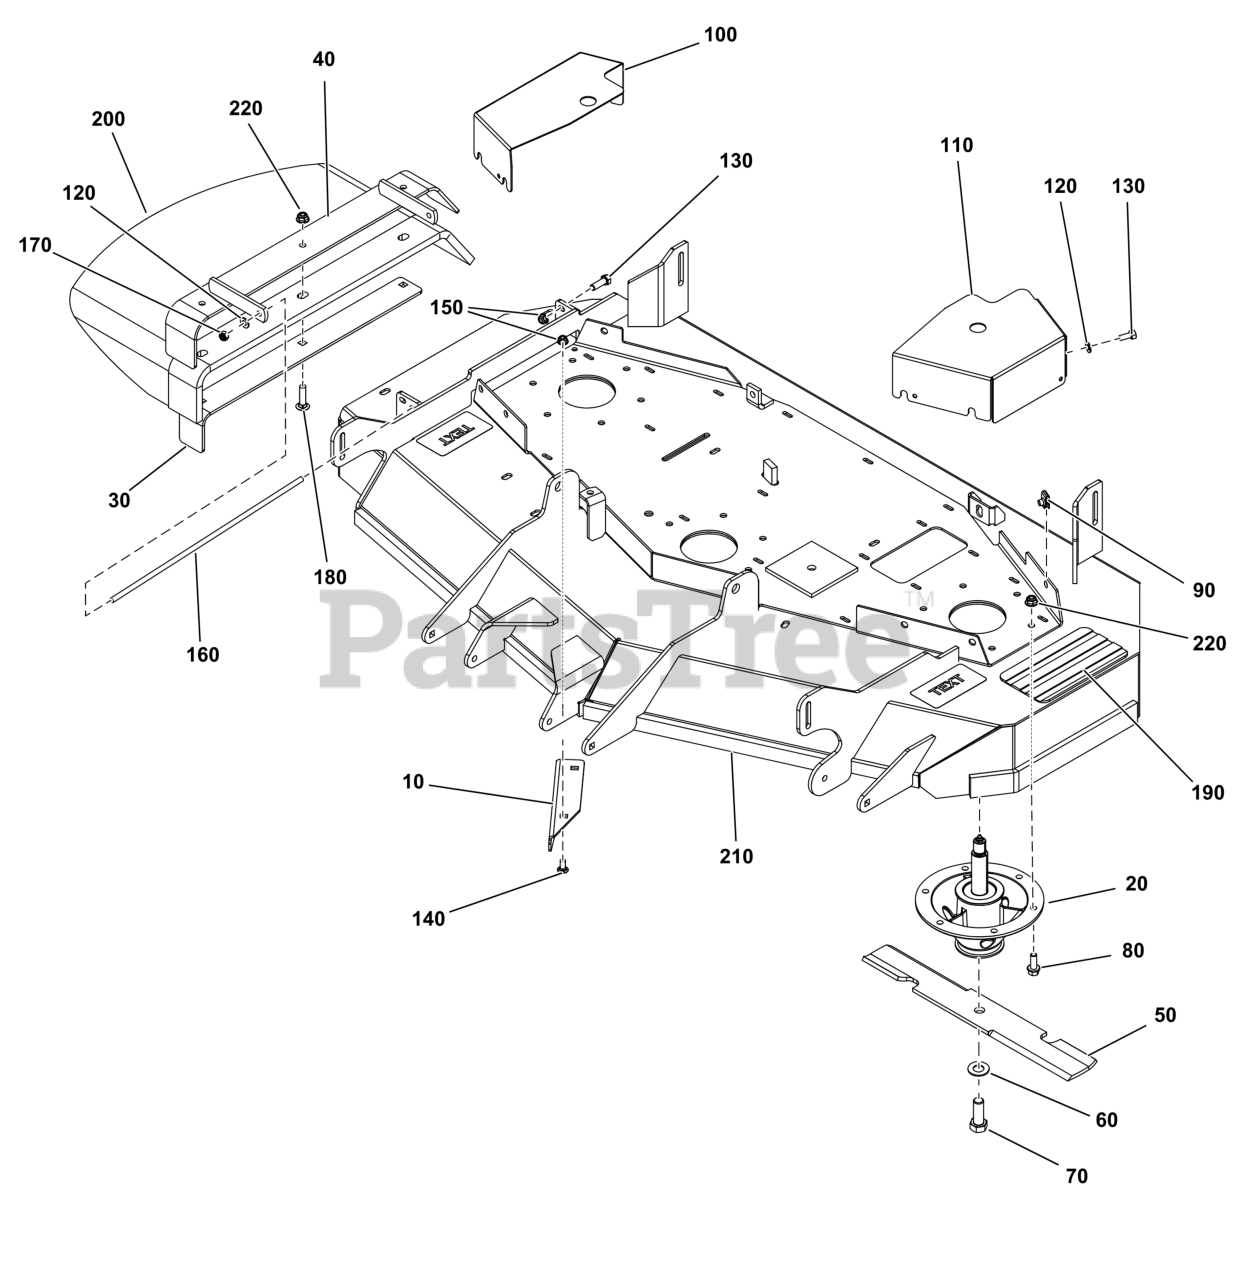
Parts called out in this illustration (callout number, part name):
10	DEFLECTOR
20	ASSEMBLY-SPINDLE
40	KIT-MOUNTING PLATE, CHUTE ROTATION
50	BLADE, 18 X .25 X 2.5, 1 X 3.5 (SET OF THREE)
60	WASHER, 5/8" YZ
70	BOLT
80	BOLT
90	BODY CLIP, 5/16-18 X
100	GUARD, PULLEY
110	GUARD, PULLEY
120	WASHER
130	BOLT, 5/16-18 X 3/4"
140	BOLT, 5/16-18 X 3/4",
150	NUT
160	ROD
170	NUT, 5/16-24 HEX NYLO
180	BOLT, 3/8-16 X 1-1/2
190	SAFETY WALK
200	CHUTE, RUBBER DISCHARGE (5104442)
210	DECK SHELL W/ DECALS, 2200-52 (5422933B)
220	NUT, 3/8-16 HEX NYLOCK
